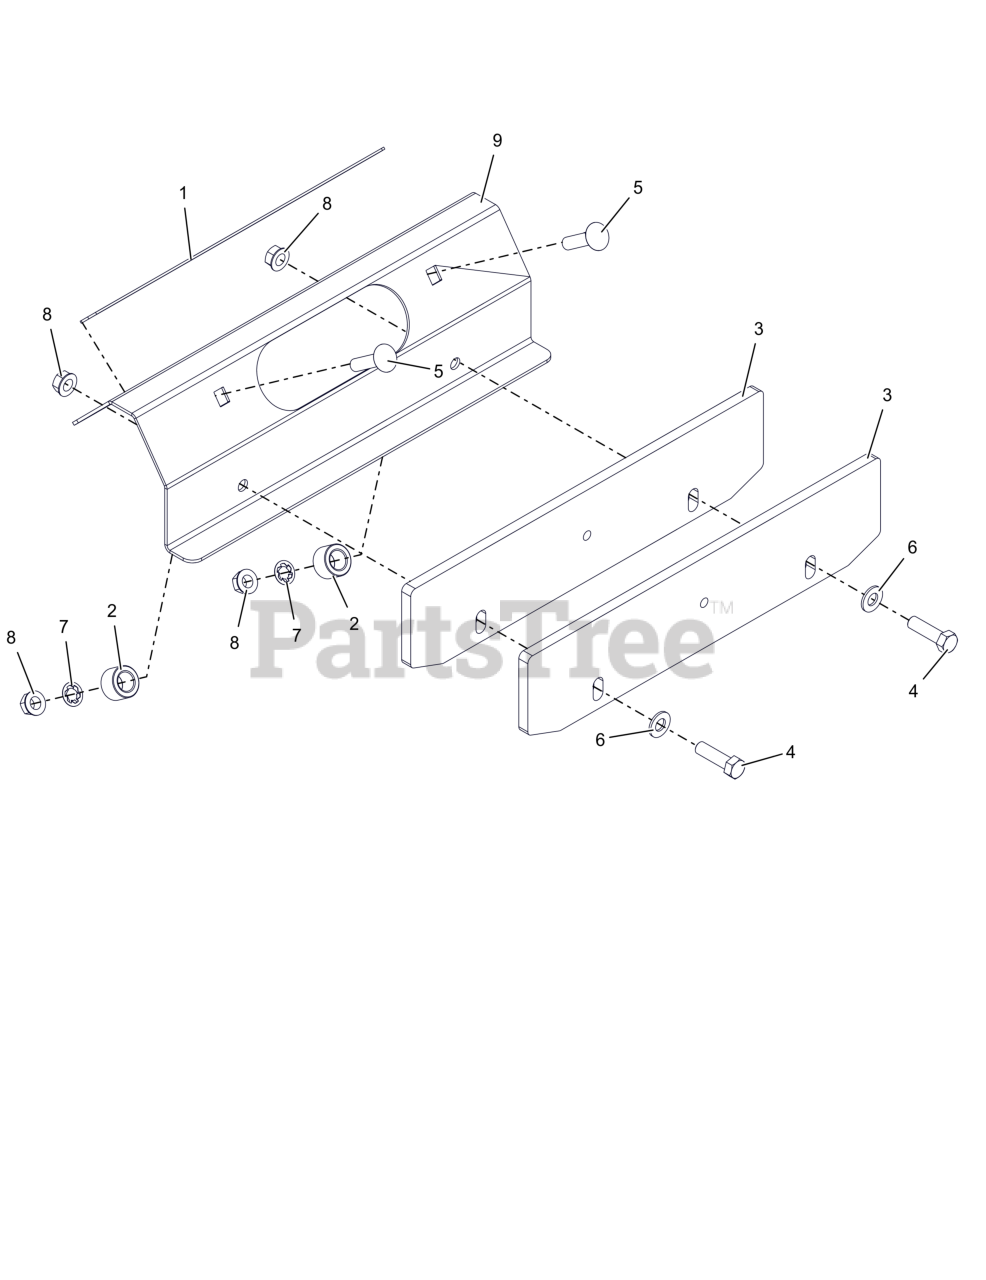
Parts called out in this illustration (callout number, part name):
1	GRIP, ADHESIVE (1" X 16" BLK)
2	TUBE, UPPER CONTROL PIVOT
3	PLATE, COUNTER WEIGHT
4	BLT, HEX .50-13X1.75 G5 ZCC
5	BLT, RHSN .50-13X2.00 G5 ZCC
6	WSHR,FLT .531X1.062X.095 ZCC
7	NUT-PUSH, .50
8	NUT-LK-CTR-FLG .500-13 GG ZCC
9	BRKT, BAGGER WEIGHT KIT (BLACK)
